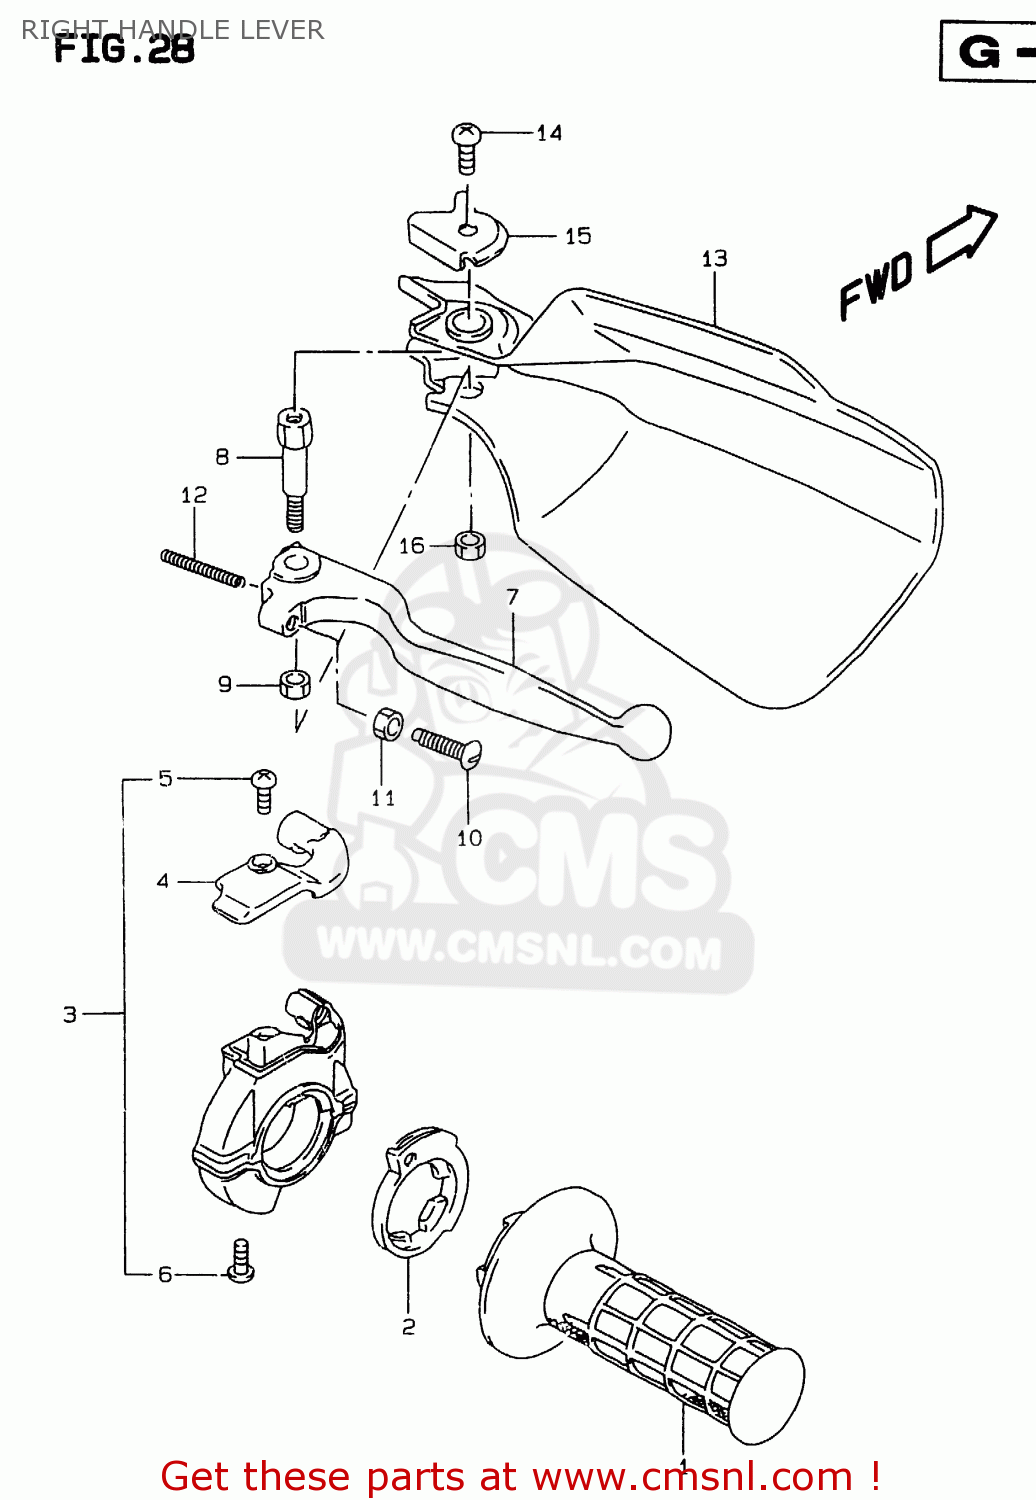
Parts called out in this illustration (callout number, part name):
1	GRIP,THROTTLE
2	ROTOR,THROTTLE GRIP
3	CASE ASSY,THROTTLE
4	COVER,THROTTLE CASE
5	SCREW,UPPER
6	SCREW
7	LEVER,BRAKE
8	BOLT,BRAKE LEVER PIVOT
9	NUT 6MM
10	BOLT,ADJUST
11	NUT
12	SPRING,RETURN
13	COVER,KNUCKLE,RIGHT
14	SCREW
15	PLATE,KNUCKLE COVER,R UPR
16	NUT 6MM
